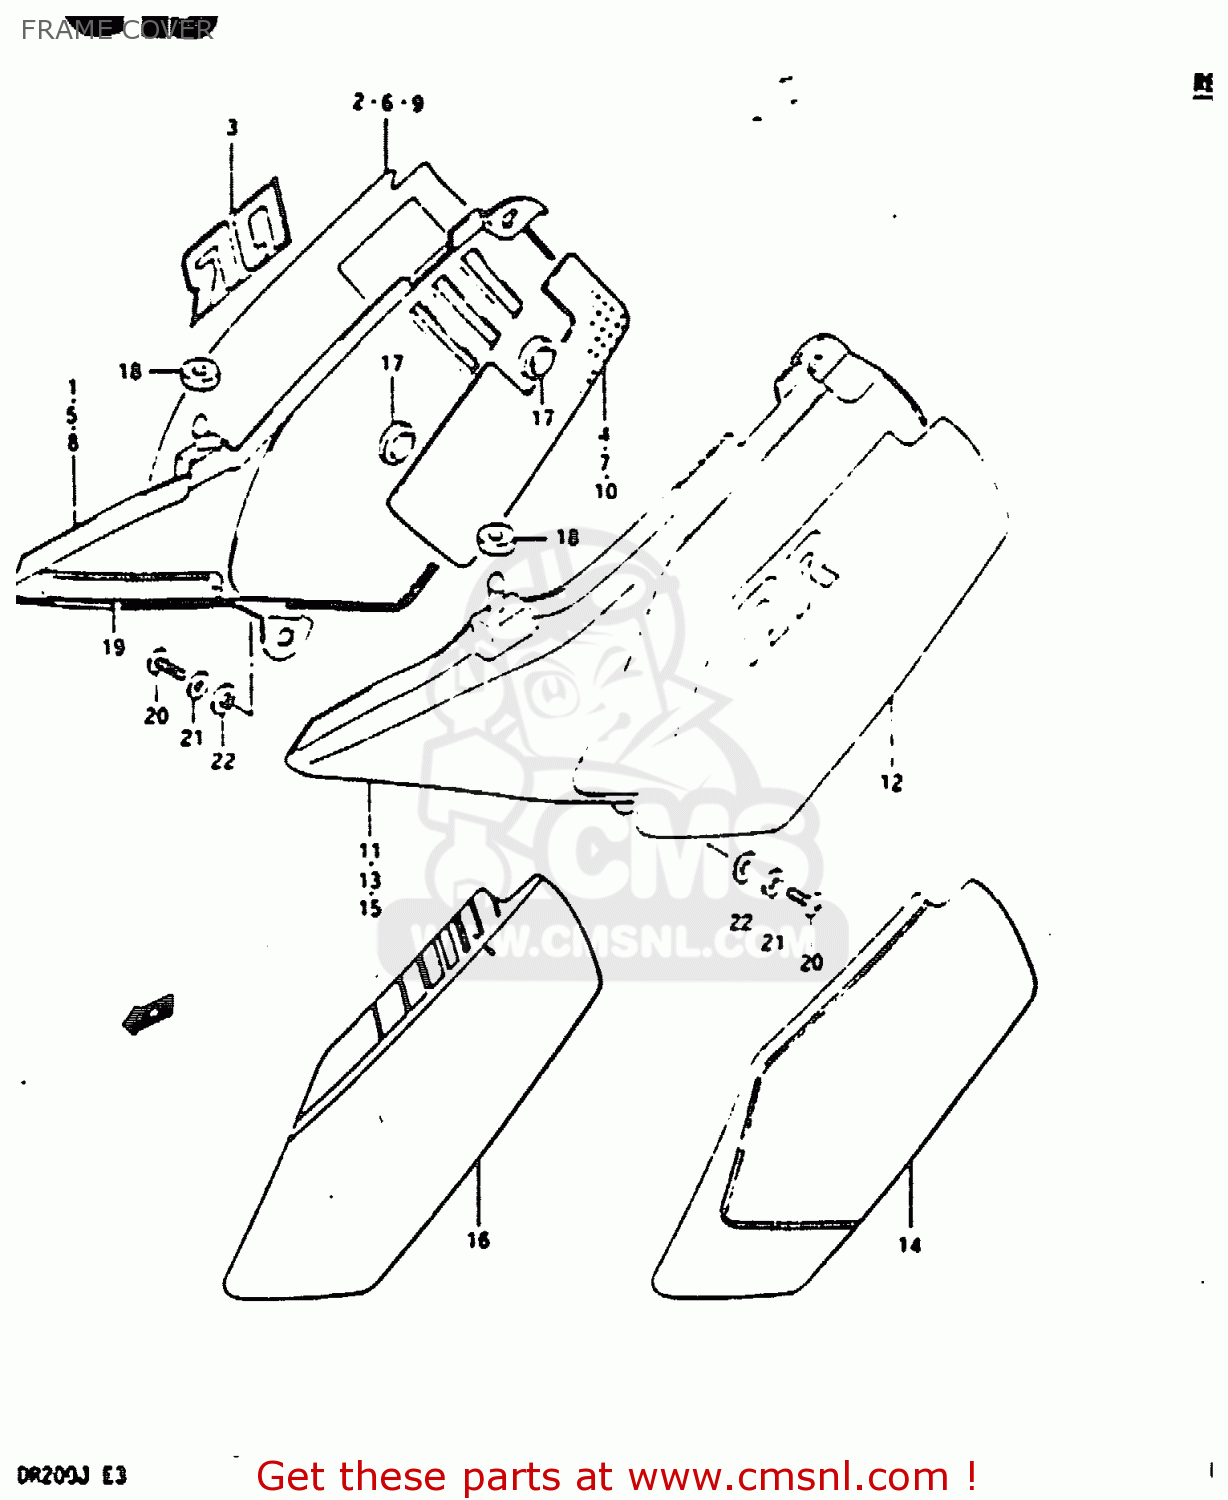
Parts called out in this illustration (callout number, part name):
1	COVER,FRAME,RIGHT
2	TAPE SET,FRAME COVER,RIGHT
3	EMBLEM,RIGHT
4	SHIELD,FRAME COVER,RIGHT
5	COVER,FRAME,RIGHT
6	TAPE SET, FRAME COVER RH
7	SHIELD,FRAME COVER,RIGHT
8	COVER COMP,FRAME,RIGHT
9	TAPE,FRAME COVER,RIGHT
10	SHIELD,FRAME COVER,RIGHT
11	COVER,FRAME,LEFT
12	TAPE SET,FRAME COVER,LEFT
13	COVER,FRAME,LEFT
14	TAPE SET,FRAME COVER,LEFT
15	COVER COMP,FRAME,LEFT
16	TAPE,FRAME COVER,LEFT
17	CUSHION
18	CUSHION,SIDE COVER BOSS
19	CUSHION,FRAME COVER
20	SCREW
21	WASHER (6.5X18X1.6)
22	WASHER
